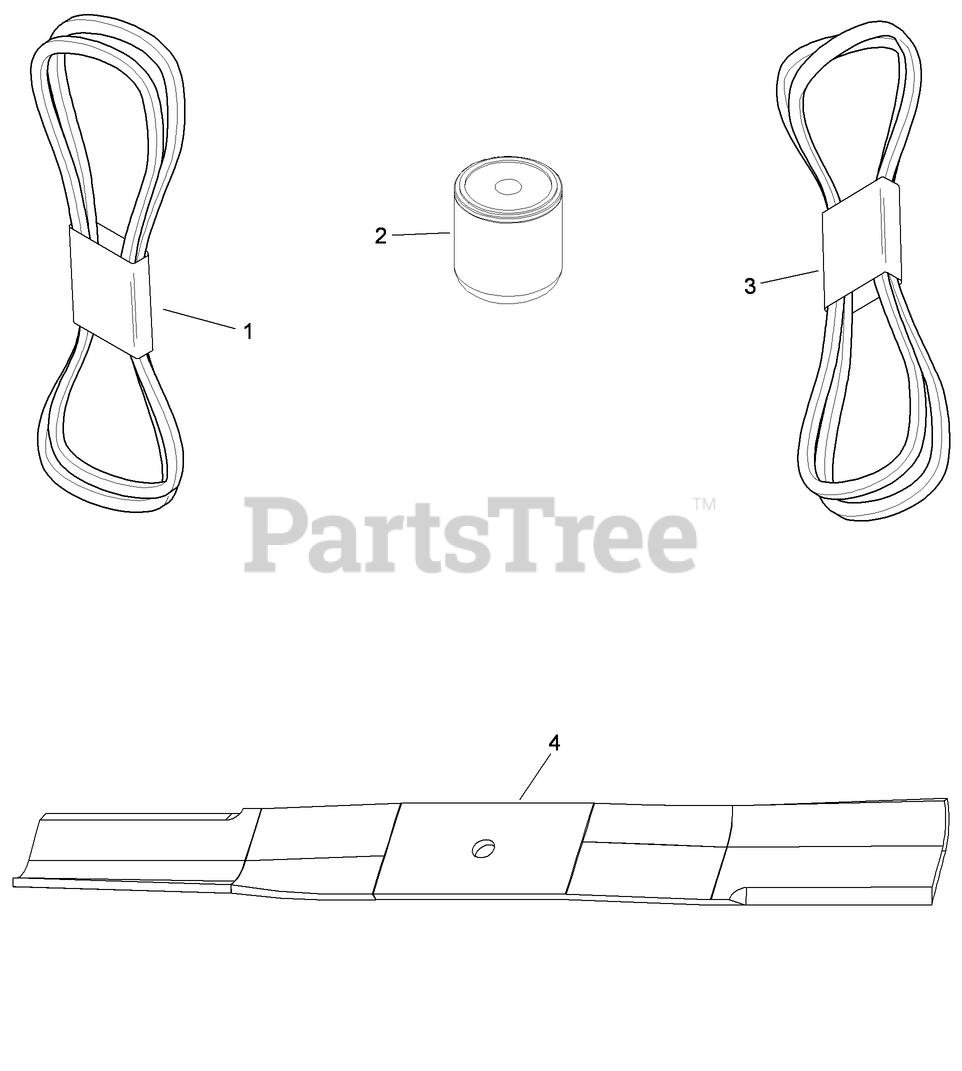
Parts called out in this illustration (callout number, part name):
1	V-BELT-DRIVE, DECK
2	FILTER-OIL, HYD
3	V-BELT
4	BLADE-21.5 INCH
